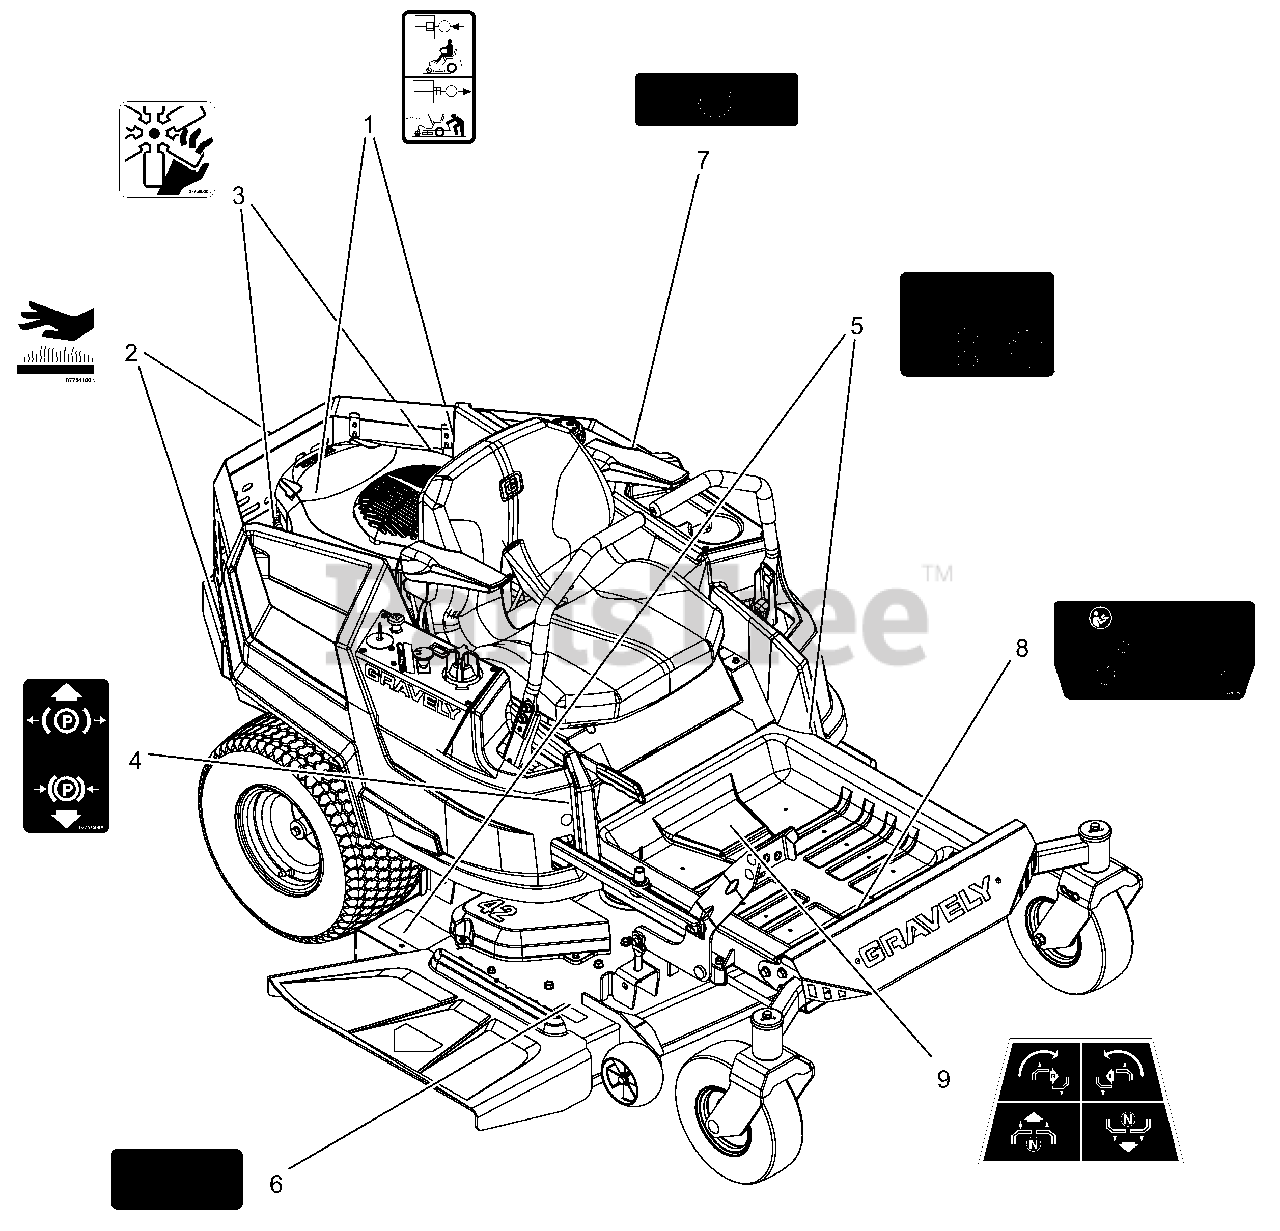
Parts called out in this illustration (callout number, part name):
1	DECAL, TRANSMISSION DISCONNECT
2	DECAL, HOT SURFACE
3	DECAL, DANGER FAN
4	DECAL, PARKING BRAKE LEVER
5	DECAL, SAFETY - MOWER DECK
6	DECAL, SAFETY - DECK GUARDING
7	DECAL-FUEL, WARNING
8	DECAL, MAIN SAFETY
9	DECAL, STEERING
